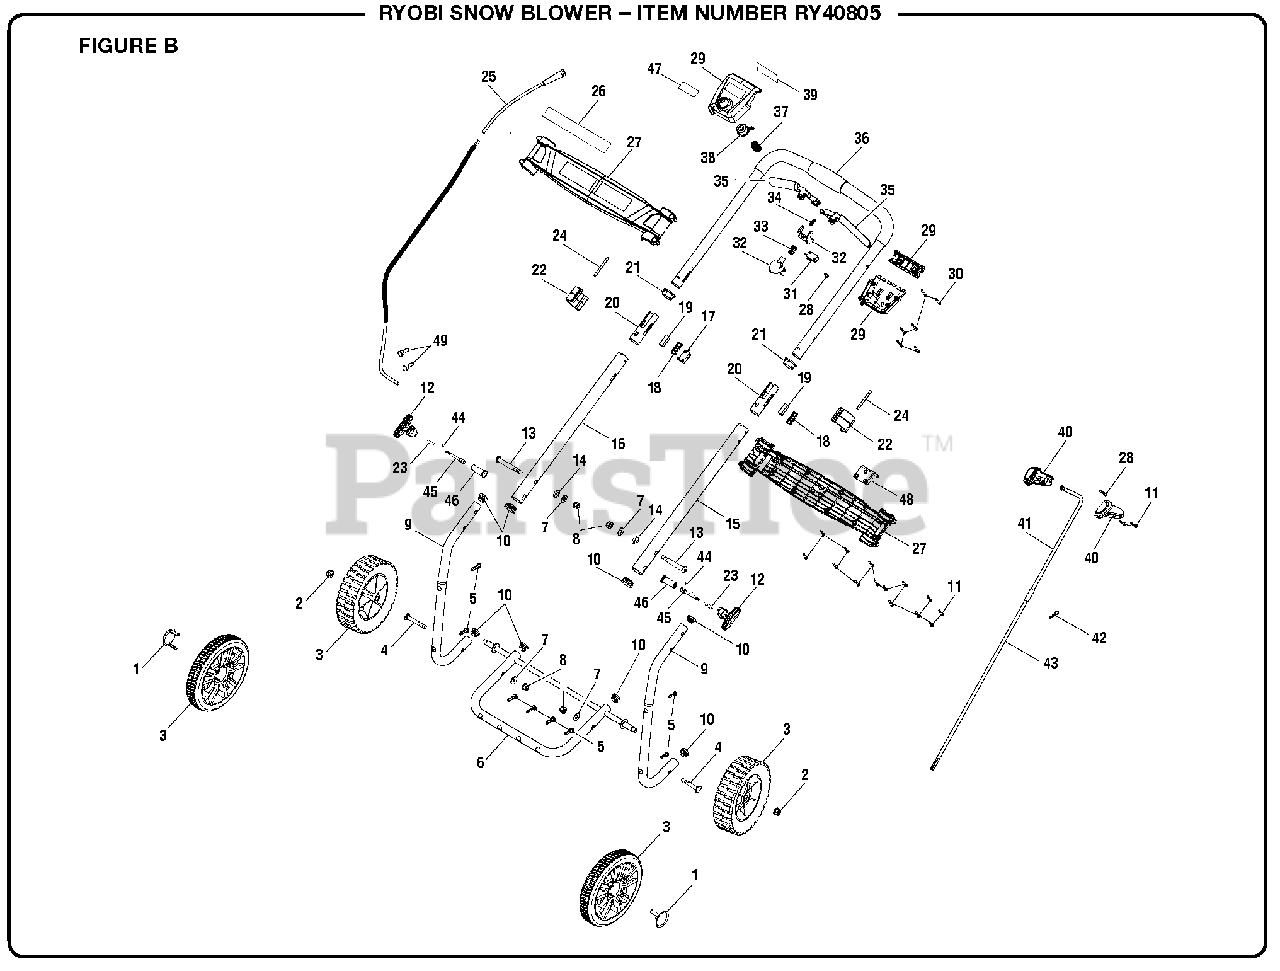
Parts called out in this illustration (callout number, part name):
1	Wheel Cover (Before Serial Number EU18234D020307)
2	Lock Nut (3/8-16)
3	8 in. Wheel Assembly (Before Serial Number EU18234D020307)
3	8 in. Wheel Assembly
4	Screw (M8 x 60 mm, Special Hd.)
5	Screw (1/4-15, T30 Torx Pan Hd.)
6	Lower Support Tube and Axle Assembly (Before Serial Number EU18234D020307)
6	Lower Support Tube and Axle Assembly
7	Washer (ID8.5 x OD20.5 x 2 mm x 2t)
8	Flange Lock Nut (M8 x 1.25 mm)
9	Lower Handle
10	End Cap Set (22 mm)
11	Screw (4 x 18 mm, T15 Torx Pan Hd.)
12	Spring Pin Adjustment Knob
13	Screw (M8 x 73 mm, T40 Torx Button Hd.)
14	Block Washer (ID10.4 x OD22 x 6.75t)
15	Left Middle Straight Tube
16	Right Middle Straight Tube
18	Locking Block
19	Rubber Gasket
20	Handle Tube Bushing
21	Straight Tube Bushing
22	Telescoping Latch
23	Compression Spring
25	Wiring Assembly
26	Mid Panel Logo Label
27	Mid Trim Housing Assembly
28	Screw (M4 x 10 mm, T20 Torx Pan Hd.)
29	Trigger Housing Assembly
30	Screw (M4 x 30 mm, T15 Torx Soc. Hd.)
31	On/Off Switch
32	Switch Button Assembly
33	Compression Spring (Trigger Handle)
34	Compression Spring (Trigger)
35	Trigger Assembly
36	Upper Handle Assembly
37	Compression Spring
38	Safety Button
39	Start Label
40	Chute Handle Assembly
41	Upper Rod
42	Hitch Pin
43	Lower Rod
44	Spring Pin
45	Detent Pin
46	Spring Pin Housing
47	Logo Label
48	Chute Support (Plastic)
49	Wire Connector
